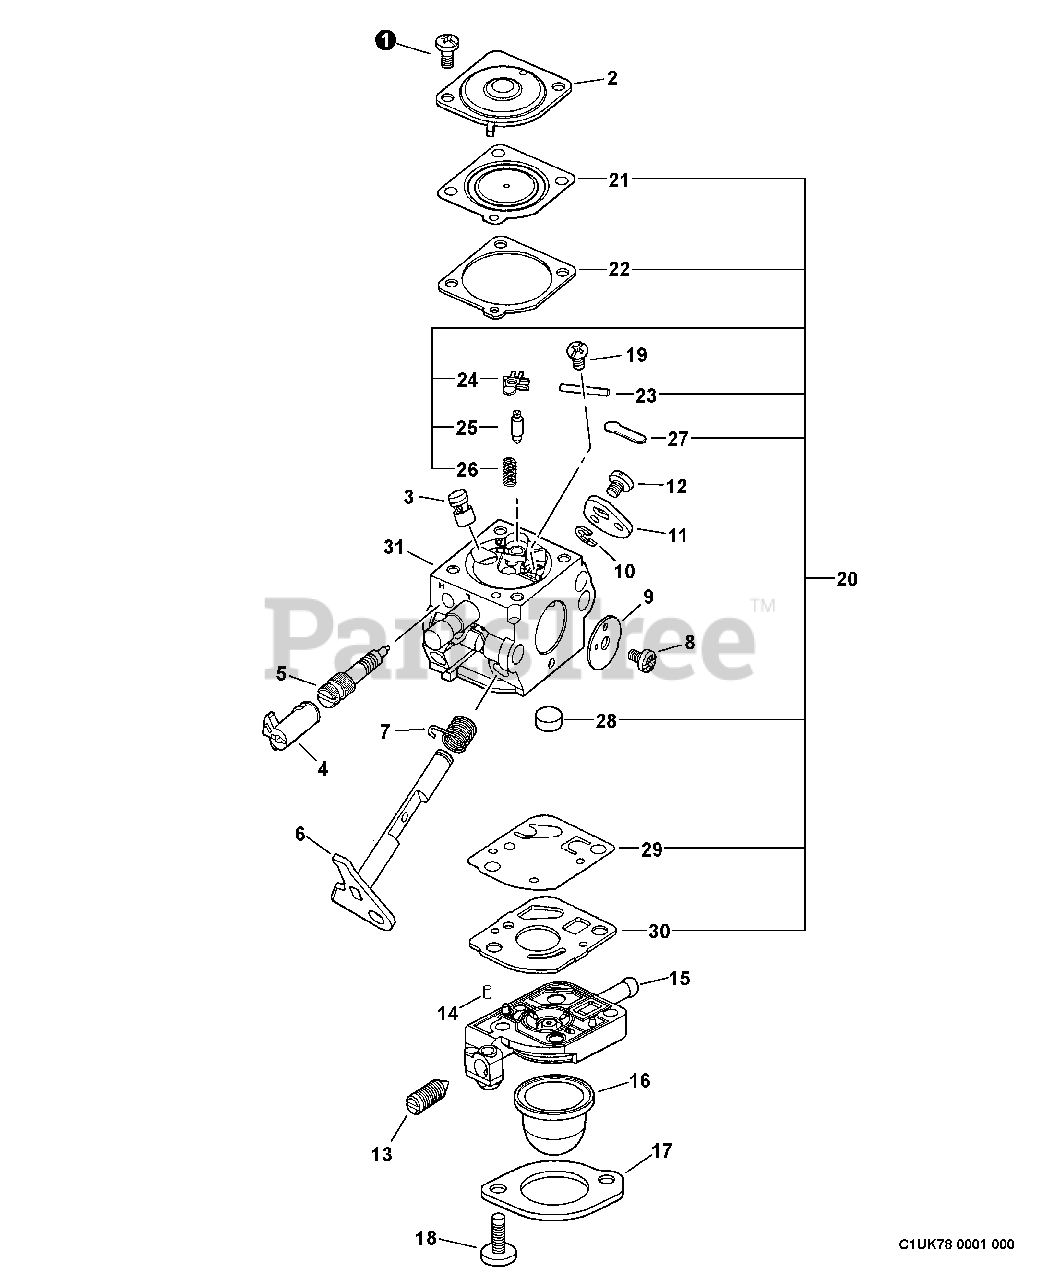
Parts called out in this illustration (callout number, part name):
2	COVER, METERING DIAPHRAGM
3	NOZZLE, CHECK VALVE
4	CAP, LIMITER
5	NEEDLE, HIGH SPEED
6	SHAFT, THROTTLE
7	SPRING, THROTTLE RETURN
9	VALVE, THROTTLE
11	LEVER, THROTTLE
14	PIECE, FRICTION
15	BODY ASSY, PURGE
16	BULB, PURGE
17	RETAINER
20	REPAIR KIT, CARBURETOR
21	DIAPHRAGM, METERING
22	GASKET, DIAPHRAGM
23	PIN, METERING LEVER
24	LEVER, METERING
25	VALVE, INLET NEEDLE
26	SPRING, METERING LEVER
27	PLUG, WELCH
28	STRAINER
29	DIAPHRAGM, PUMP
30	GASKET, PUMP
31	BODY, CARBURETOR
